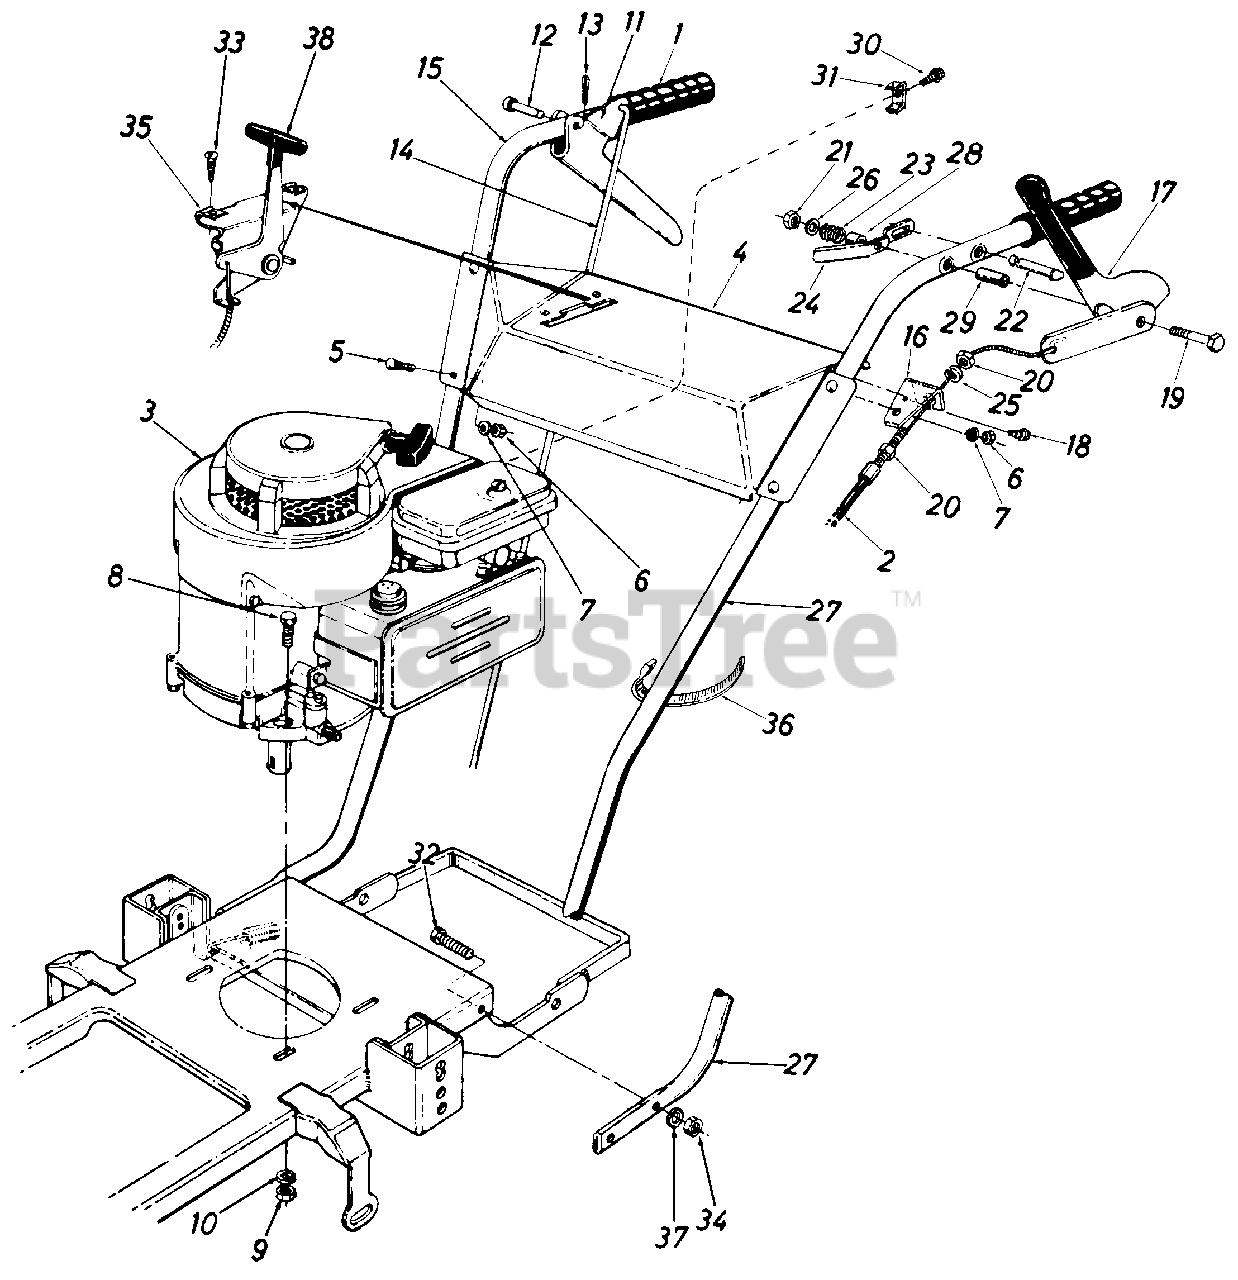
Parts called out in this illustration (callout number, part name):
2	Clutch Cable 39.0"
3	Engine
4	Handle Panel
5	Carr. Bolt 5/16-18 x 1.75" Lg.
6	Hex Nut 5/16-18 Thd.
7	L-Wash. 5/16" I.D.*
8	Hex Bolt 5/16-24 x 1.25" Lg.
9	Hex Nut 5/16-24 Thd.
10	L-Wash. 5/16" I.D.
11	Clutch Grip Ass'y.
12	Clevis Pin .375" Dia.
13	Intern. Cotter Pin 5/16" Dia.
14	Drive Control Rod
15	Handle R.H.
16	Clutch Cable Brk't.
17	Blade Clutch Grip Ass'y.
18	Hex Wash. S-Tap Scr. 1/4-20 x .50" Lg.
19	Hex Bolt 1/4-20 x 2.25" Lg.
20	Hex Jam Nut 5/16-24 Thd.
21	Hex Cent. L-Nut 1/4-20 Thd.
22	Lock Pin
23	Compression Spring
24	Lockout Spring
25	L-Wash. 5/16" I.D.*
26	Internal Tooth L-Wash.
27	Handle L.H.
28	Spacer.44" Lg.
29	Spacer 1.03" Lg.
30	Hex AB-Tap Scr. #10 x .38" Lg.
31	Casing Clamp
32	Hex Bolt 5/16-24 x 1.25" Lg.
33	Hex Wash. Hd. AB-Tap Scr. #10 x .50" Lg.
34	Hex Nut 5/16-24 Thd.
35	Speed Nut 10Z U-Type
36	Cable Tie
37	L-Wash. 5/16" I.D.
38	Throttle Control
